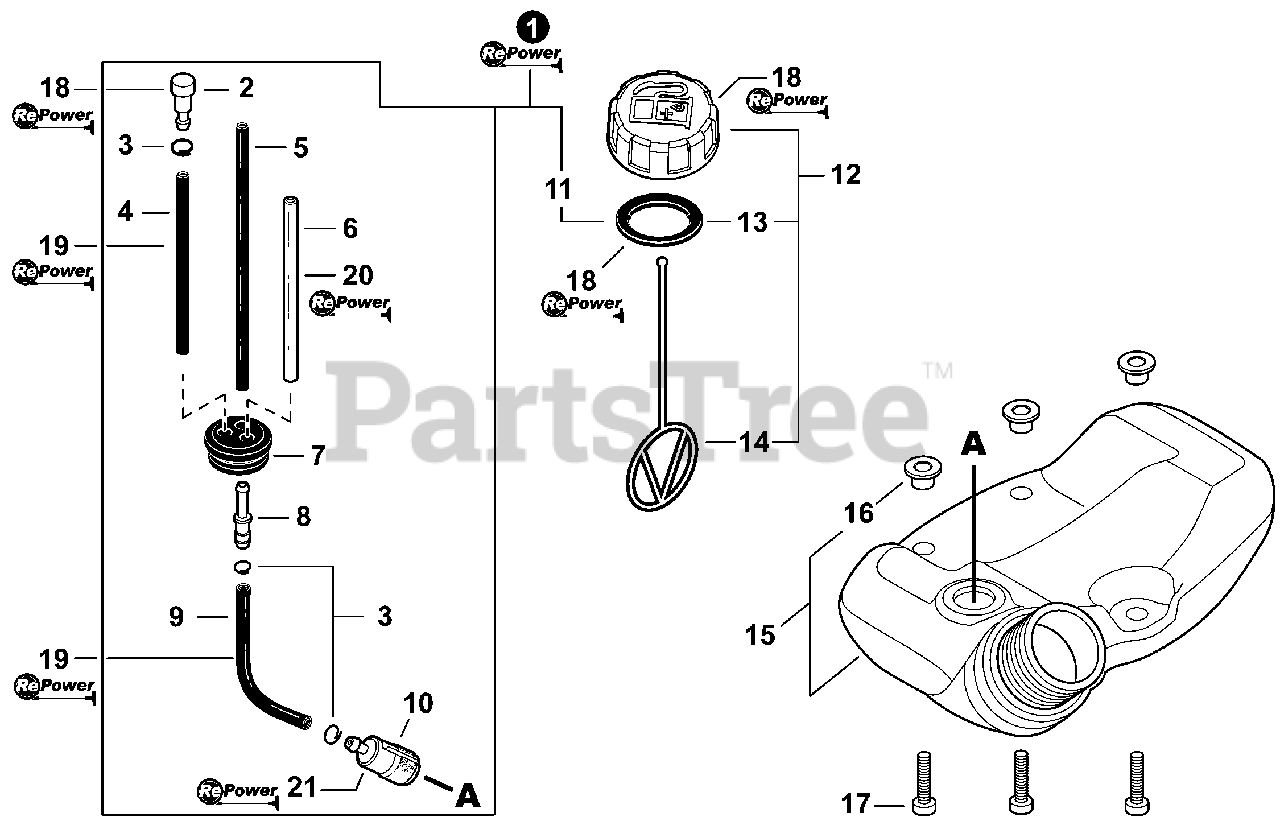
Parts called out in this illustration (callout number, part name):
1	FUEL SYSTEM KIT - REPOWER
2	VENT ASSY
4	PIPE, FUEL 3×5×90 BLACK
5	PIPE, FUEL 3×5×74 BLACK
6	PIPE, FUEL 3×6×80 CLEAR
7	GROMMET, FUEL 5
8	CONNECTOR, PIPE 5×3.5
9	PIPE, FUEL 3×5×130
10	FILTER, FUEL
11	GASKET, FUEL CAP
12	CAP ASSY, FUEL
13	GASKET, FUEL CAP
14	CONNECTOR, CAP L= 123
15	TANK ASSY, FUEL
16	COLLAR 5
17	BOLT, TORX 5×20
18	CAP/VENT KIT - REPOWER
19	PIPE, FUEL - REPOWER BULK 3×5mm BLACK
20	PIPE, FUEL - REPOWER BULK 3×6mm CLEAR
21	TUNE-UP KIT - REPOWER
